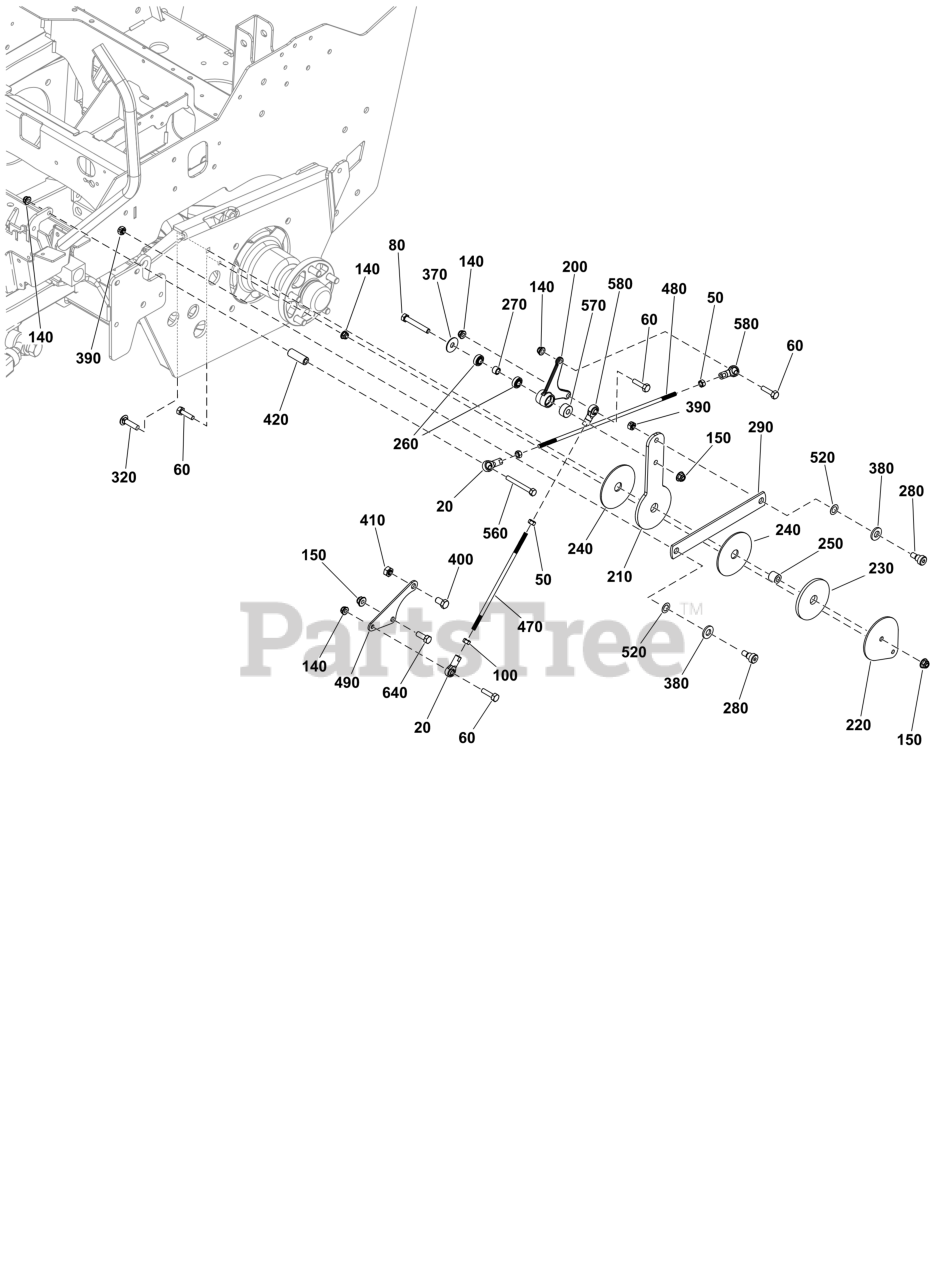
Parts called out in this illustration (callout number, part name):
20	BALL JOINT 5/16-24 RH
50	NUT, 5/16-24 HEX, LH
60	BOLT, 5/16-18 X 1-1/4
140	NUT
150	NUT, 3/8-16 HEX NYLOCK
200	PIVOT, CONTROL SYSTEM
210	PLATE, CTRL SYST ARM
220	PLATE, CTRL SYSTEM LK
230	PAD, .77 X 3.50 X .25
240	PAD, CONTROL SYSTEM
250	SPACER, .39X.75X.69
260	BEARING, .375ID
270	SPACER, .39X.55X.38
280	BOLT, 3/8-16 X 3/8",
290	LINK, CONTROL SYSTEM ARM, IS2100 - BLK
320	BOLT, 3/8-16 X 1-1/2
370	WASHER, 3/8" FENDER
380	WASHER, 1/2" YELLOW
390	NUT, 3/8-16 HEX SIDE
400	BOLT, 7/16-14
410	NUT, 7/16-14 HEX
470	ROD, 5/16-24
480	ROD, HYDRO LINKAGE
490	PLATE, CONTROL MOUNT
520	WAVE WASHER
560	BOLT, 5/16-18 X 2-3/4
580	BALL JOINT 5/16-24 LH
640	BOLT, 3/8-16 X 1" GD5
